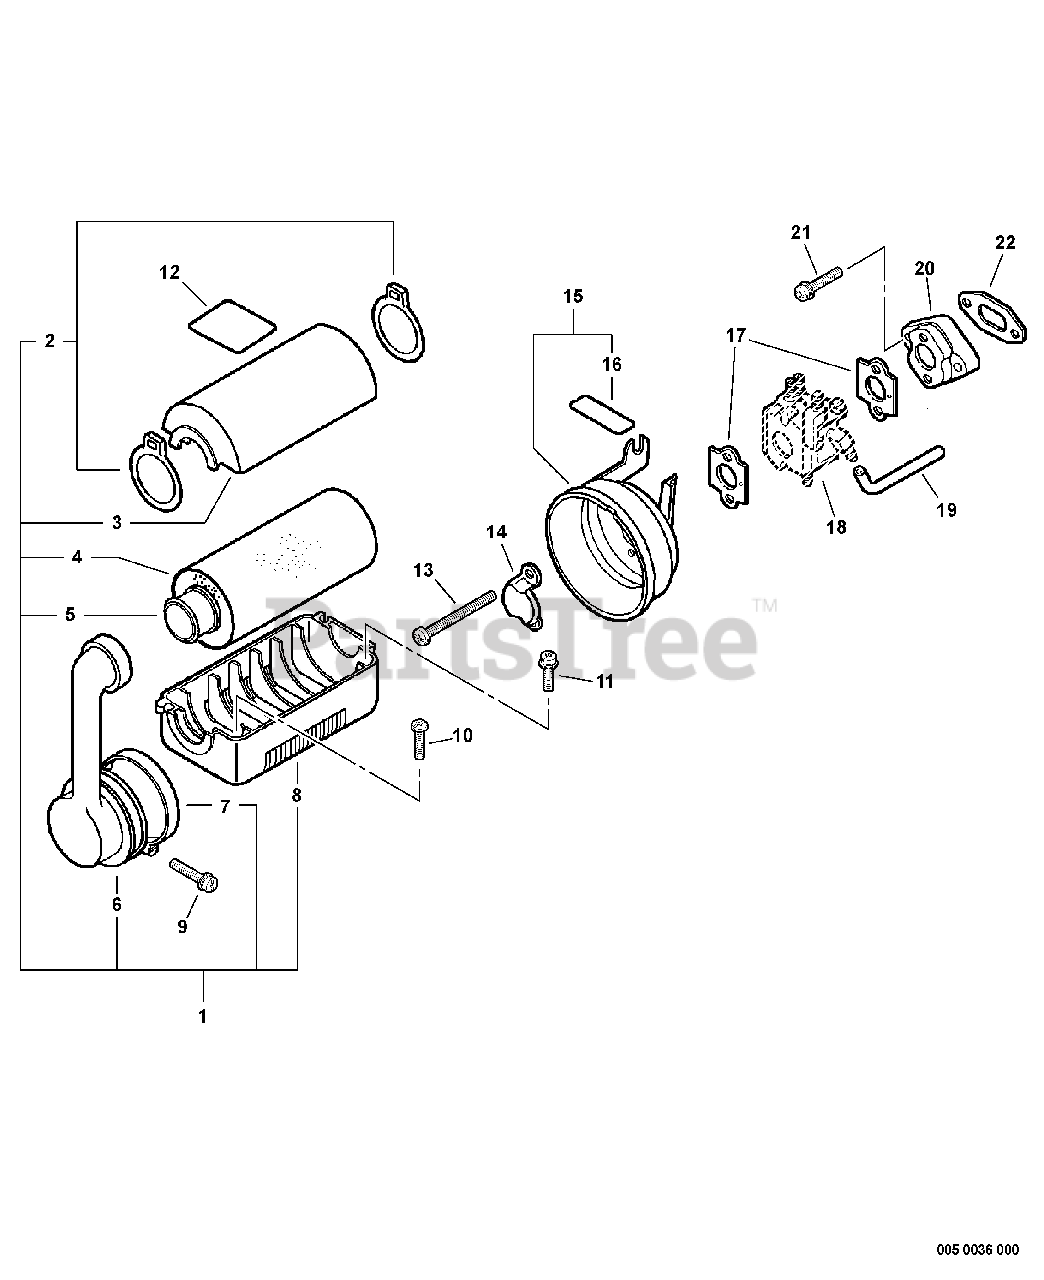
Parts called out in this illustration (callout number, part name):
1	AIR CLEANER ASSY
3	COVER, AIR FILTER
4	FILTER, AIR
5	FILTER, AIR
6	ADAPTOR, INTAKE
8	CASE, AIR FILTER
9	SCREW - 5X30
10	SCREW - 6X15
11	SCREW - 6X20
12	LABEL - CAUTION
13	SCREW - 5X55
14	PLATE, PREVENT
15	CASE, AIR FILTER
16	LABEL - CHOKE
17	GASKET, INTAKE
18	CARBURETOR
19	PIPE - IMPULSE
20	INSULATOR, INTAKE
21	SCREW - 6X25
22	GASKET, INTAKE
